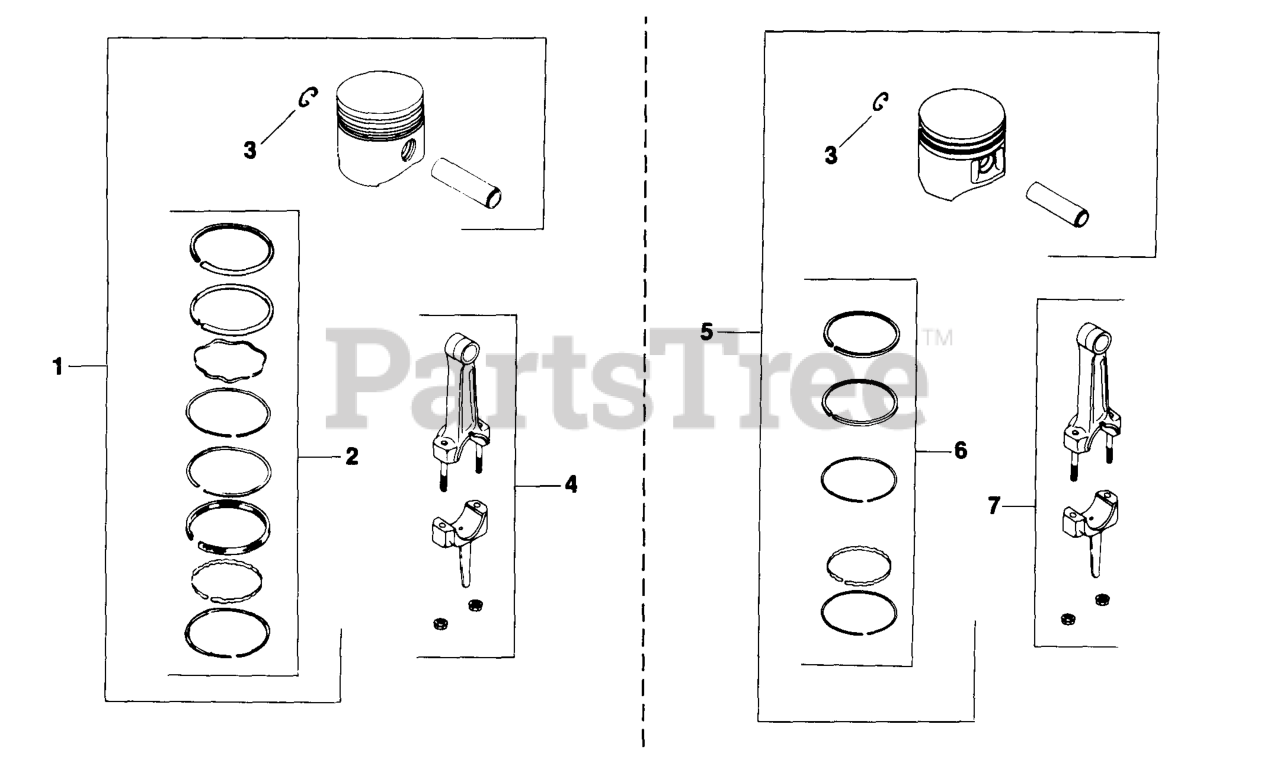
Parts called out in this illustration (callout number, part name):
1	KIT, PISTON W/RING SET STD - DISCONTINUED
1	KIT, PISTON W/RING SET .003
1	PISTON W/RING SET .010
1	PISTON W/RING SET .020 - DISCONTINUED
1	KIT, PISTON W/RING SET .030 - DISCONTINUED
2	RING SET - USE 48 108 05
2	RING SET - USE 48 108 06
2	RING SET - USE 48 108 07
2	RING SET - USE 48 108 08
4	ROD STD. - DISCONTINUED
4	ROD .010 - DISCONTINUED
5	PISTON W/RING SET STD - DISCONTINUED
5	PISTON W/RING SET .003 - (#DSC)
5	PISTON W/RING SET .010 - DISCONTINUED
5	KIT, PISTON W/RING SET .020 - DISCONTINUED
5	PISTON W/RING SET .030 - DISCONTINUED
6	RINGS STD-DISCONTINUED
6	RINGS .010 - DISCONTINUED
6	RINGS .020
6	RINGS .030 - DISCONTINUED
